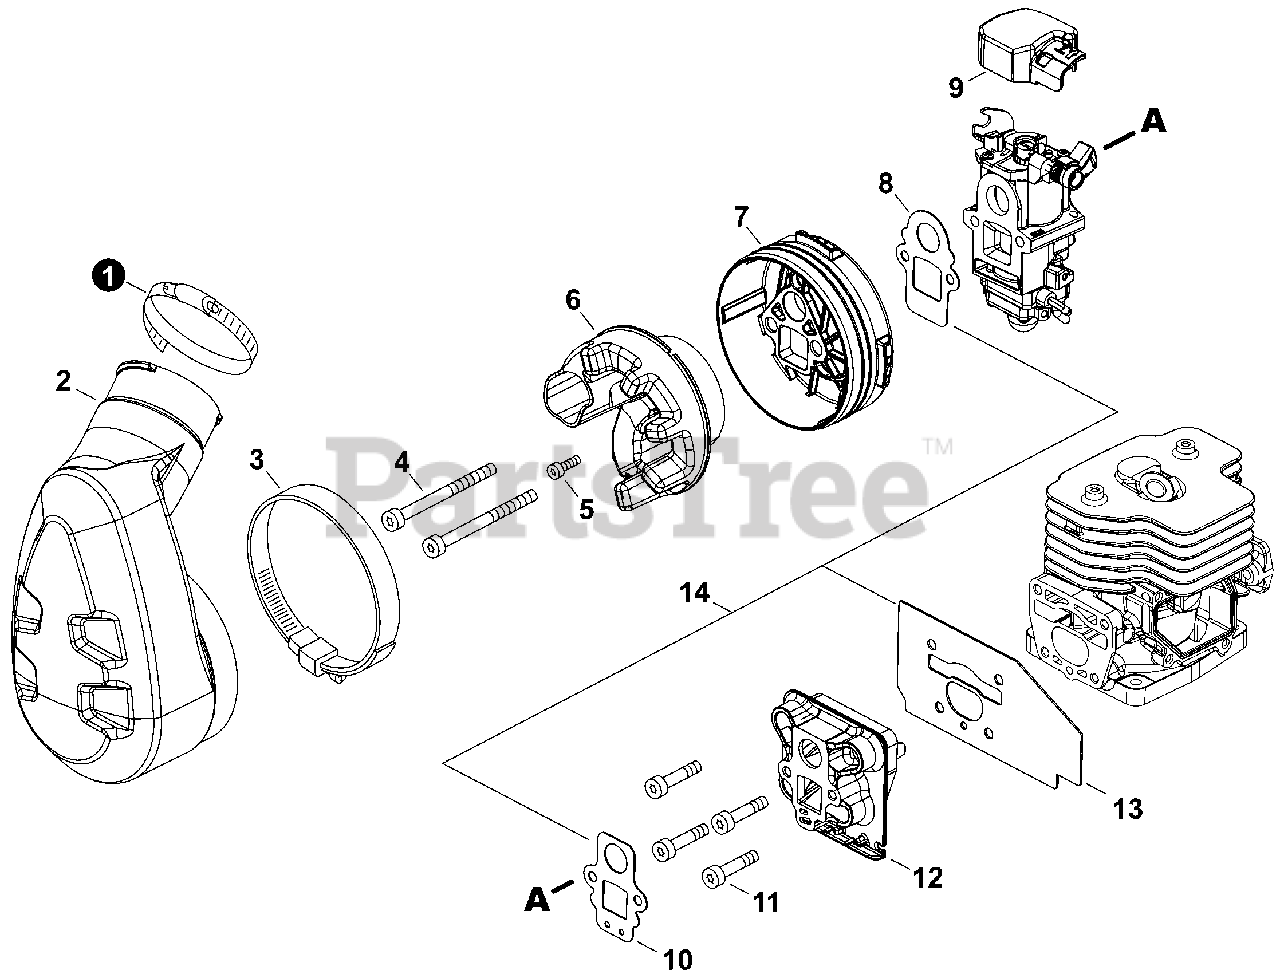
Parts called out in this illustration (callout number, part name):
1	CLAMP - BAND 33 MM /57 MM
2	ADAPTOR, AIR FILTER
3	CLAMP - BAND 77.8 MM / 101.6 MM
4	BOLT, TORX 5x65
5	BOLT, TORX 4x12
6	DUCT, AIR
7	BRACKET, AIR FILTER
8	GASKET, INTAKE
9	CAP, CARBURETOR
10	GASKET, INTAKE
11	BOLT 5x25
12	INSULATOR, INTAKE
13	HEAT SHIELD, INTAKE
14	GASKET KIT: ENGINE, INTAKE, EXHAUST
